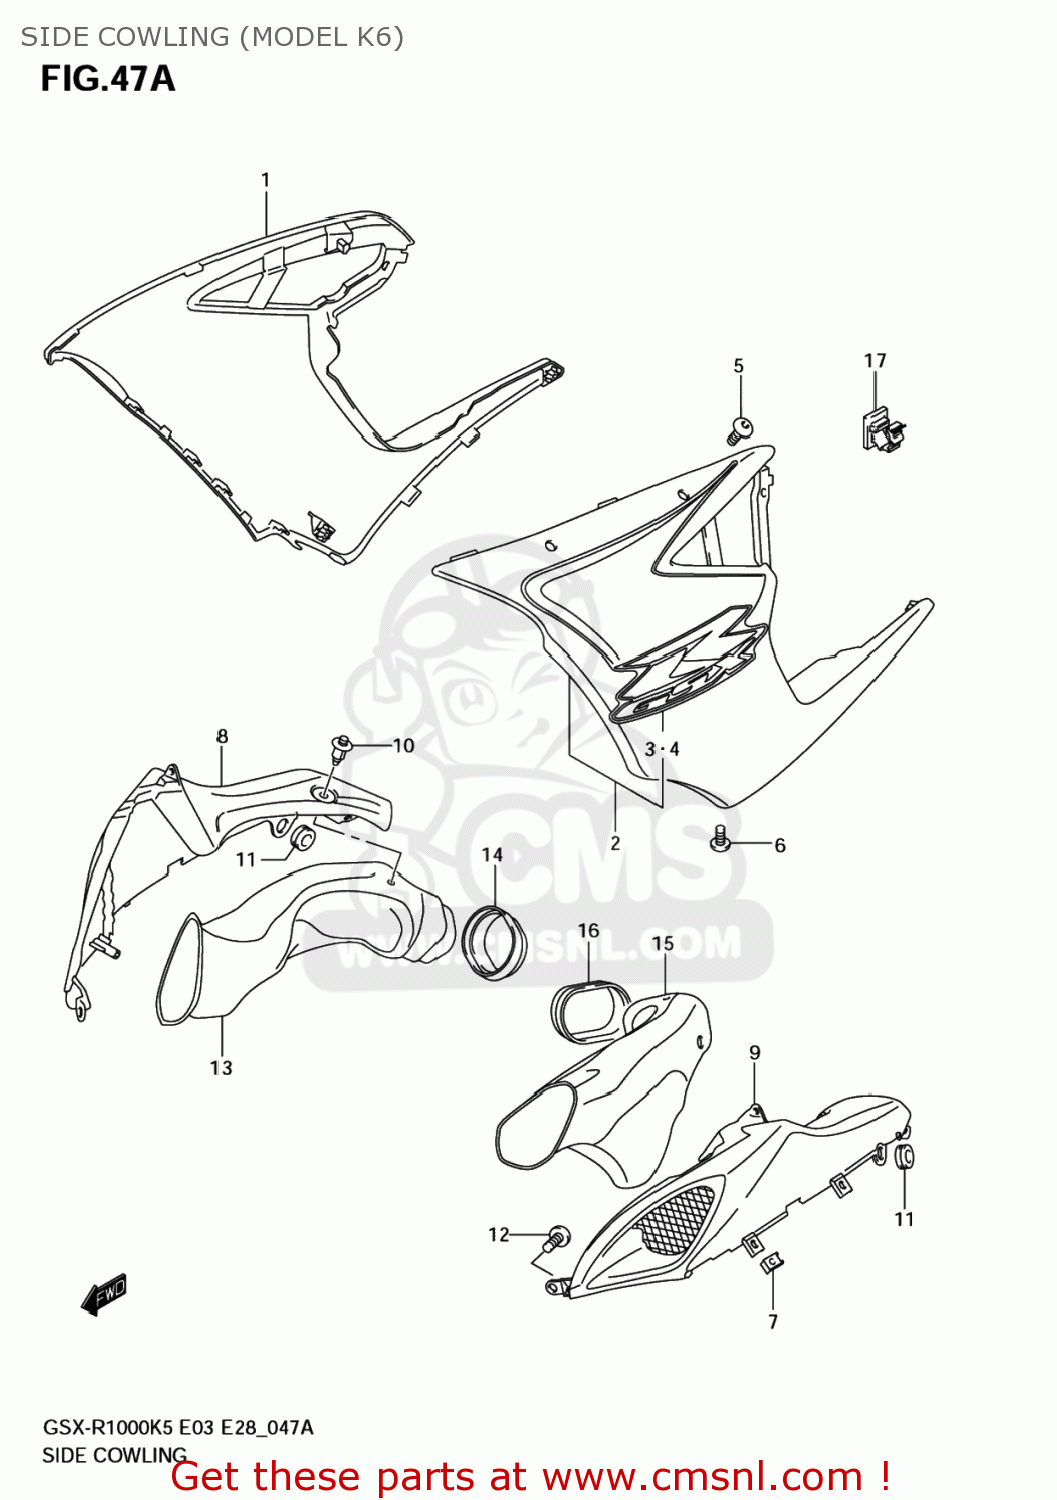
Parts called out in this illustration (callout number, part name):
1	COWLING,SIDE,R
2	COWLING,SIDE,L
3	TAPE,COWL SIDE,R
4	TAPE,COWL SIDE,L
5	SCREW(5X13)
6	SCREW(5X16)
7	NUT,COWL
8	COVER,INTAKE,R(BLACK)
9	COVER,INTAKE,L(BLACK)
10	CLIP
11	CUSHION
12	SCREW(5X12)
13	PIPE,AIR INTAKE,R
14	MOLDING,AIR INTAKE,R
15	PIPE,AIR INTAKE,L
16	MOLDING,AIR INTAKE,L
17	CLAMP
